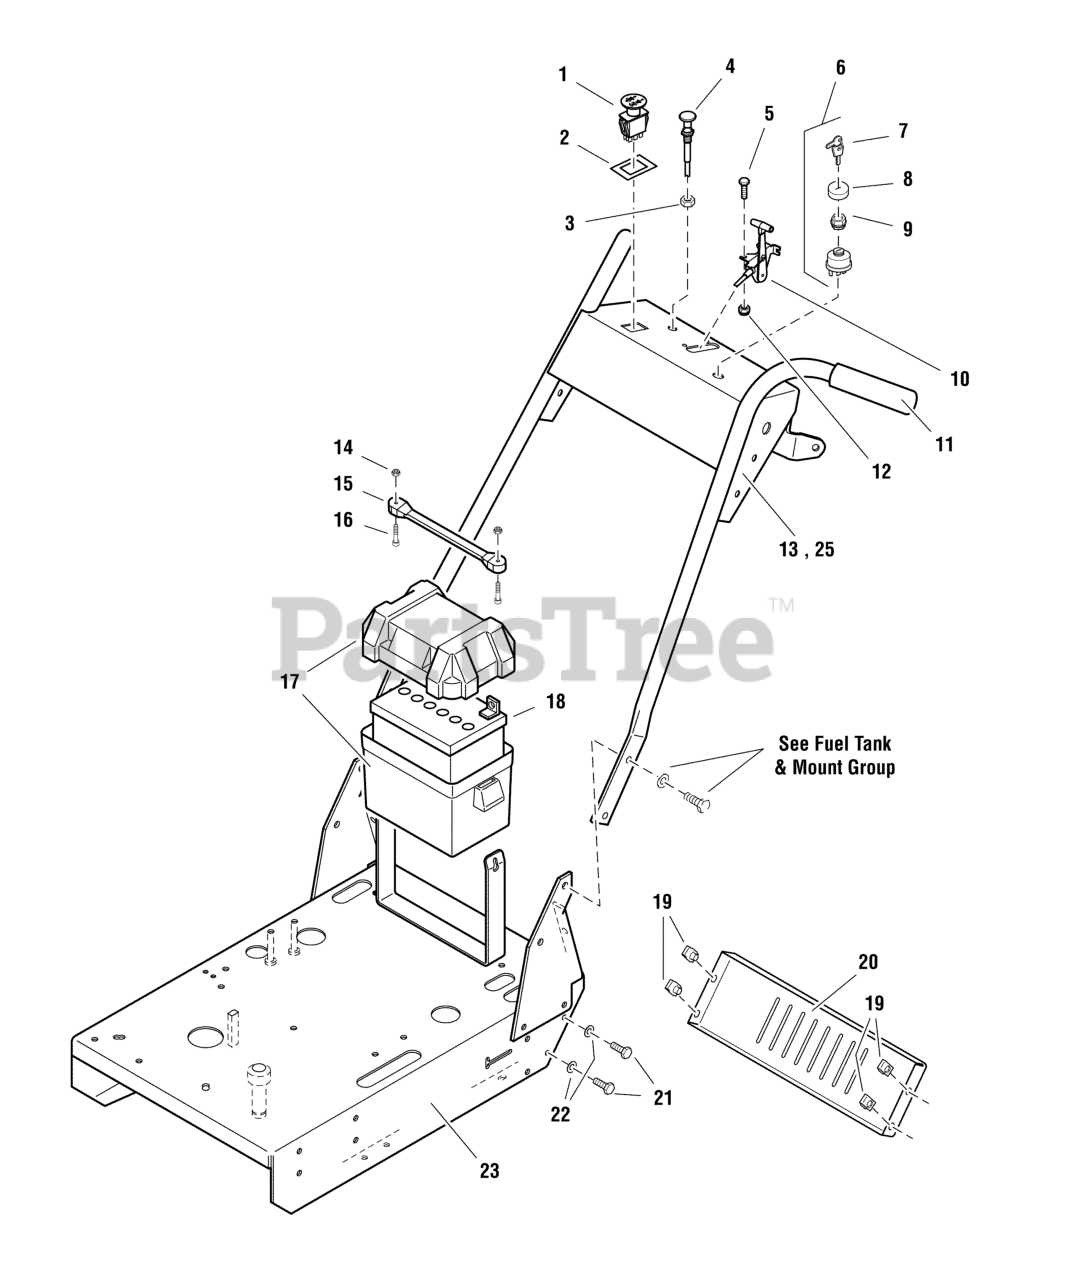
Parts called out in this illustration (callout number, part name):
1	SWITCH, BLADE ENGAGEMENT
2	RING, SWITCH RETAINER
3	NUT, 3/8-24 HEX
4	CABLE, CHOKE CONTROL, 47"
5	BOLT, 1/4-20 X 3/4" GD5 YZ
6	SWITCH, IGNITION, 6 POST
7	KEY, IGNITION MOLDED SET
8	COVER, PLASTIC, SNAP ON
9	PLASTIC NUT
10	CABLE, THROTTLE CONTROL, 48"
11	GRIP, FOAM, .940" X 4.62" X .187"
12	NUT, 1/4-20 HEX NYLOCK FLANGE
13	WELD, HANDLE BAR, TD
14	NUT, #10-24 HEX NYLON LOCK
15	STRAP, RUBBER
16	SCREW, #10-24 X 1 RS, CZ
17	BATTERY BOX, W/ DRAIN HOLE
18	BATTERY
19	BODY CLIP, 5/16-18-7GA MATERIAL
20	SHIELD, REAR
21	BOLT, 5/16-18 X 1" GD5 YZ
22	WASHER, 5/16" SAE
23	WELD, ENGINE DECK, HC36
24	NUT, 1/4-20 HEX SERR. FLANGE
25	WELD, HANDLE BAR, TD
